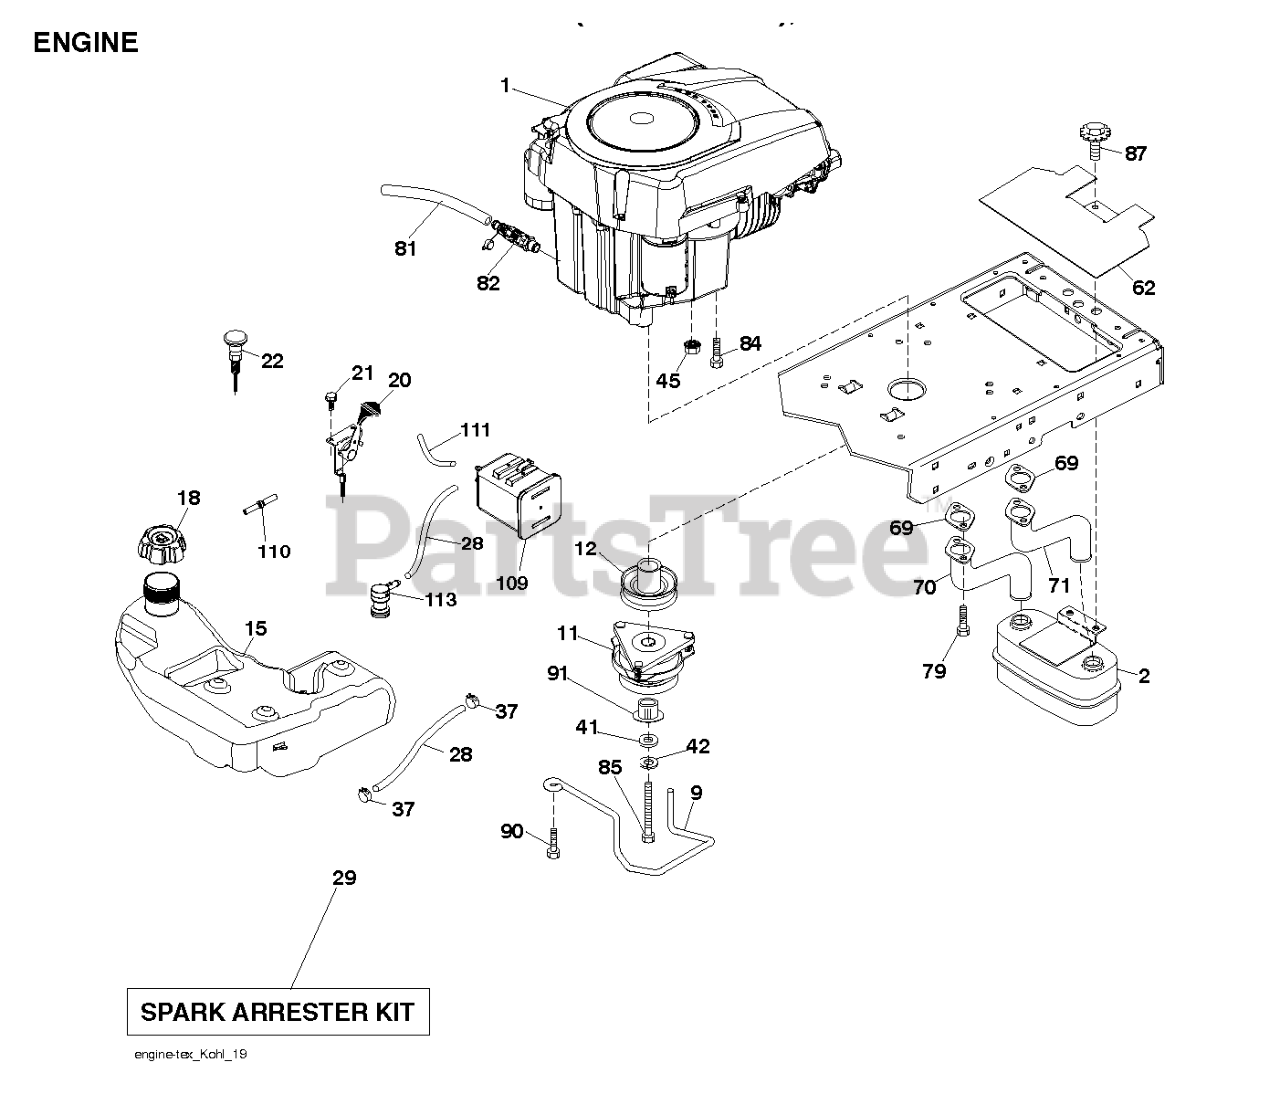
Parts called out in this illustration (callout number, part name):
2	MUFFLER.TWIN.CYL.LOW.TONE
9	KEEPER.BELT.ENGINE.4.2
11	CLUTCH MZ ZTR GT.48/54"1.125"
12	PULLEY ENGINE
15	RP TANK.ASM.FUEL.4GA.CARB
18	CAP.ASM.FL.RITCH.3"E10.SYM.498
20	THROTTLE CONTROL
21	SCREW.#10 X 0.750.BOS
22	CONTROL.CHOKE.ERGO.PUSH-IN.BLA
28	LINE.FUEL.64"REAR.EMIS
29	KIT.SPARK ARRESTOR 794945 B&S
37	HOSE CLAMP
42	LOCKWASHER
45	NUT
62	SHIELD.HEAT.MUFFLER
69	GASKET.EXHAUST.KOHL.CV18-CV26
70	RP.PIPE-EXHAUST LH
71	RP.PIPE-EXHAUST RH
79	SCREW.SOCKET HD.5/16-1
81	TUBE, DRAIN OIL ASM.
82	VALUE.OIL.DRAIN
84	SCREW 3/8-16X1
85	BOLT HEX 7/16-20 X 3.75 GR. 5
87	BOLT.5/16-18UNCX1.W/SEMS.BLK
90	SCREW 3/8-16X1
91	BUSHING.1.375OD
109	CANNISTER, CARBON
110	VALVE.ASM.ANTI-SLOSH
111	PURGE.LINE.36"REAR.CALIFORNIA
113	VALVE.SLANT.CARTRDG.90 DEG.TEX
